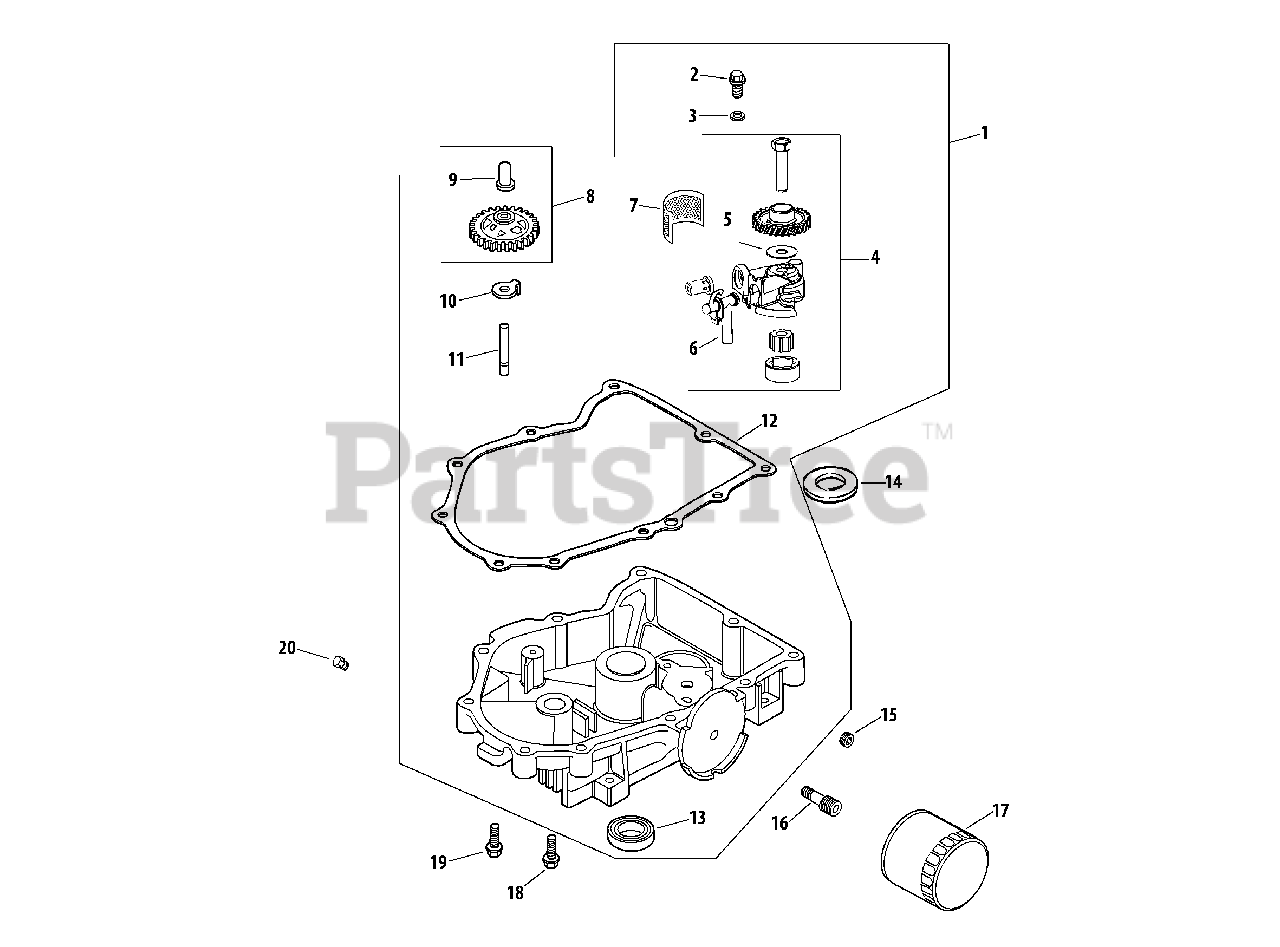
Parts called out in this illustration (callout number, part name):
1	Oil Pan Assembly Kit (Inc. 2-10)
2	Screw
4	Oil Pump Assembly Kit (Inc. 5 & 6)
6	Oil Pick-Up Tube (CV)
8	Governor Gear Kit w/ Pin (Inc. 9)
12	Oil Pan Gasket
16	Oil Filter Nipple
18	Hex Flange Screw
19	Hex Flange Screw
